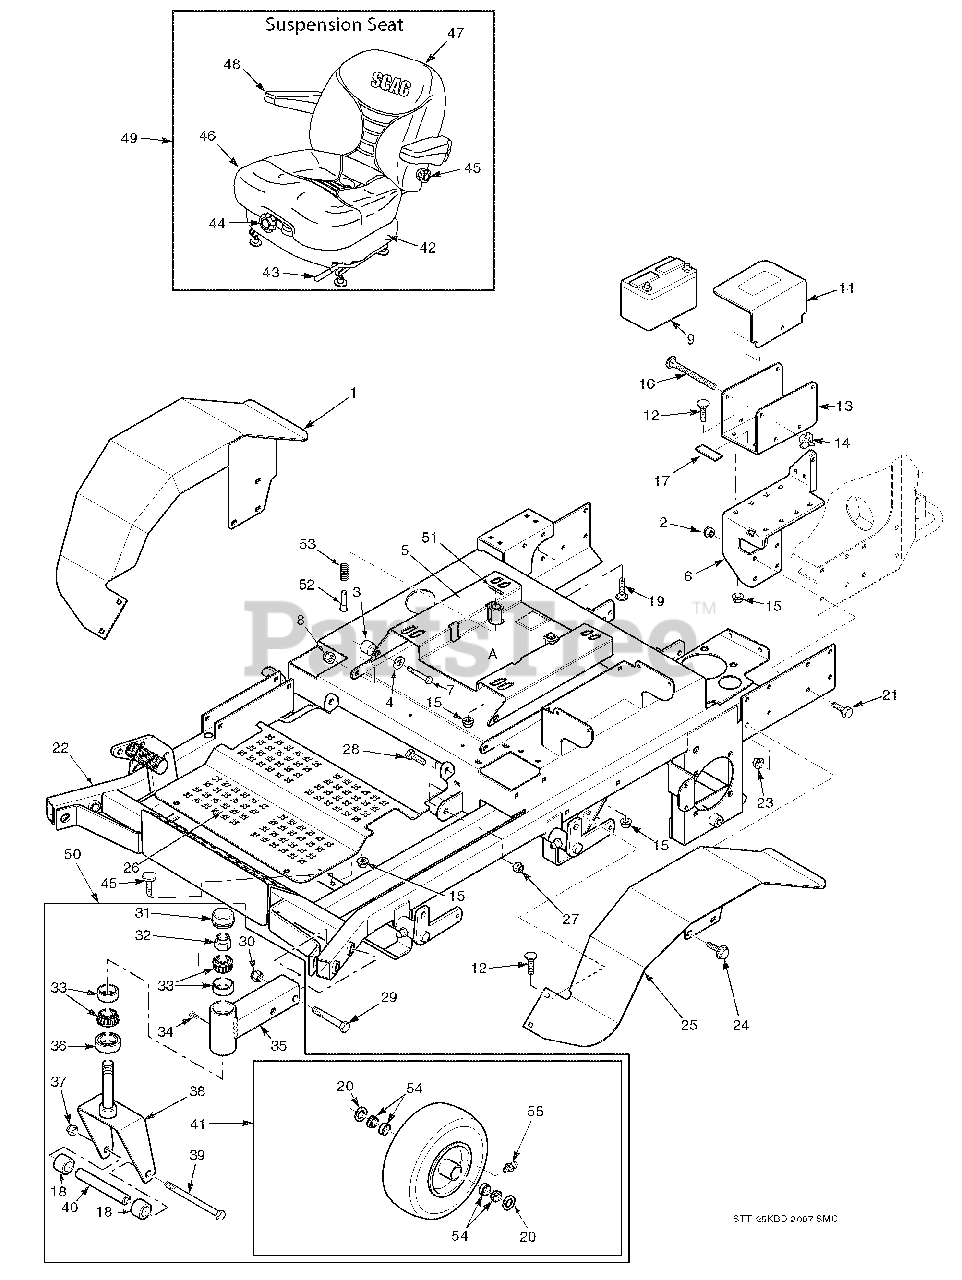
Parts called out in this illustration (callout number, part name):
1	Fender Weldment, RH
2	Nut, Elastic Stop 3/8-16
3	Spacer
4	Flatwasher, 3/8-.391 x .938 x .105
5	Seat Plate Weldment
6	Battery Box Mount
7	Bolt, Hex Head 3/8-16 x 2.0”
8	Nut, Elastic Stop 3/8-16
9	Battery
10	Pad, Battery Cover
11	Cover, Battery
12	Bolt, Carriage 5/16-18 x 3/4"
13	Plate, Battery Box
14	Wing Nut, 1/4-20 x 3/4"
15	Nut, Hex Serrated Flange 5/16-18
16	Bolt, Carriage 1/4-20 x 7-1/2"
17	Rubber Pad
18	Spacer, Caster Wheel
19	Bolt, Carriage 5/16-18 x 1"
21	Bolt, Hex Head 3/8-16 x 1”
22	Main Frame
23	Nut, Hex Serrated Flange 3/8-16
24	Screw, Hex Serrated Flange 3/8-16 x 1”
25	Fender Weldment, LH
26	Foot Plate
27	Nut, Hex Elastic Stop 3/8-16
28	Bolt, Hex Head 3/8-16 x 1”
29	Bolt, Hex Head 5/8-11 x 4”
30	Nut, Hex Elastic Stop 5/8-11
31	Cap, Grease
32	Nut, Hex Elastic Stop 1.0-14
33	Bearing W/Race
34	Plug, 1/4-28 THD Form
35	Extention Weldment, Caster 61A
36	Seal, 2.00 OD. x 1.625 Bore
37	Nut, Hex Elastic Stop 1/2-13
38	Yoke Weldment, Caster
39	Bolt, Hex Head 1/2-13 x 9-1/2”
40	Sleeve, Caster Wheel
41	Wheel Assembly
42	Shock Absorber Kit
43	Seat Adjustment, Track Set
44	Weight Adjustment Kit
45	Lumbar Kit
46	Seat Cushion Kit
47	Back Cushion Kit
48	Armrest Only
49	Suspension Seat Assembly w/seat belt
50	Caster Wheel Assy 61V
51	Roll Pin, Spring 5/32 x 3/4”
52	Pin Retainer, Spring
53	Spring, Seat
54	Bearing w/ Race
55	Grease Fitting
